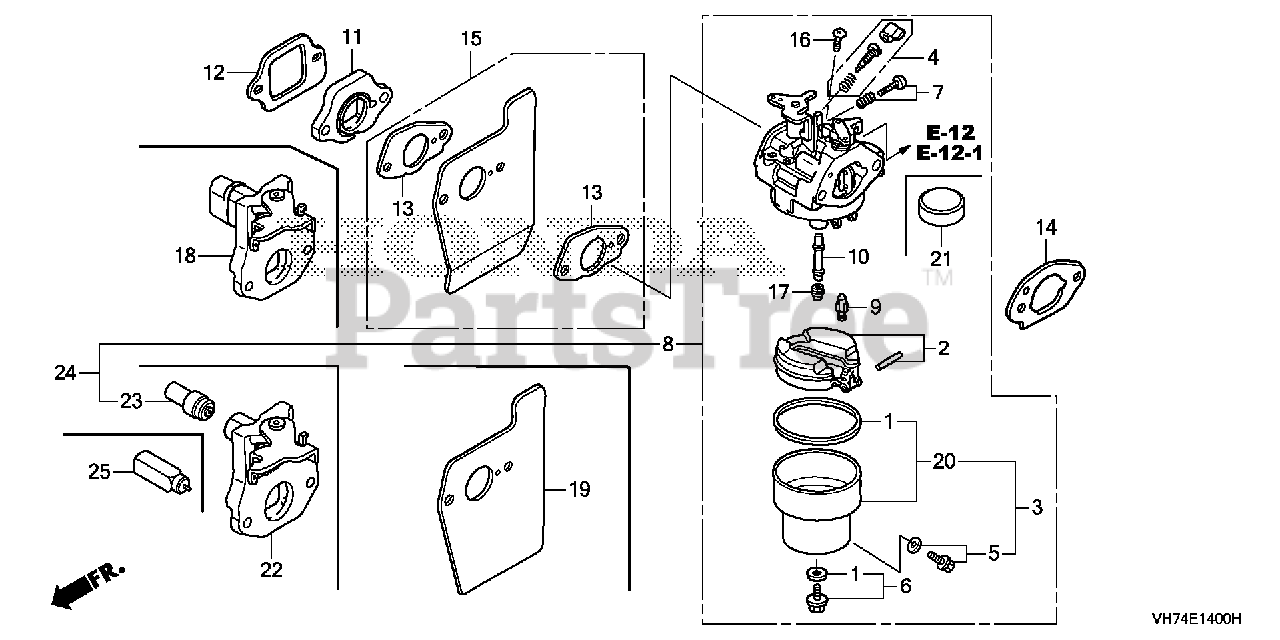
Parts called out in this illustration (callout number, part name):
1	GASKET SET
2	FLOAT SET
4	SCREW SET (CARBURETOR NO.)
6	SCREW SET B
6	SCREW SET
7	SCREW SET (THROTTLE STOP) (CARBURETOR NO.)
8	CARBURETOR ASSY. (BB75F B)
9	VALVE, FLOAT (Honda Code 7934714). (CARBURETOR NO.)
10	NOZZLE, MAIN (CARBURETOR NO.)
12	GASKET, INSULATOR
16	SCREW, PAN (5X6)
17	JET, MAIN (#65) Use up to Engine SN BB30A D.
17	JET, MAIN (#68) Use up to Engine SN BB30A D.
17	JET, MAIN (#62) (Honda Code 0635482). (CARBURETOR NO.)
19	GUIDE, AIR
20	CHAMBER SET, FLOAT (CARBURETOR NO.)
21	CAP, CHOKE DUST (CARBURETOR NO.)
22	CONTROL ASSY., CHOKE
25	THERMO WAX ASSY.
